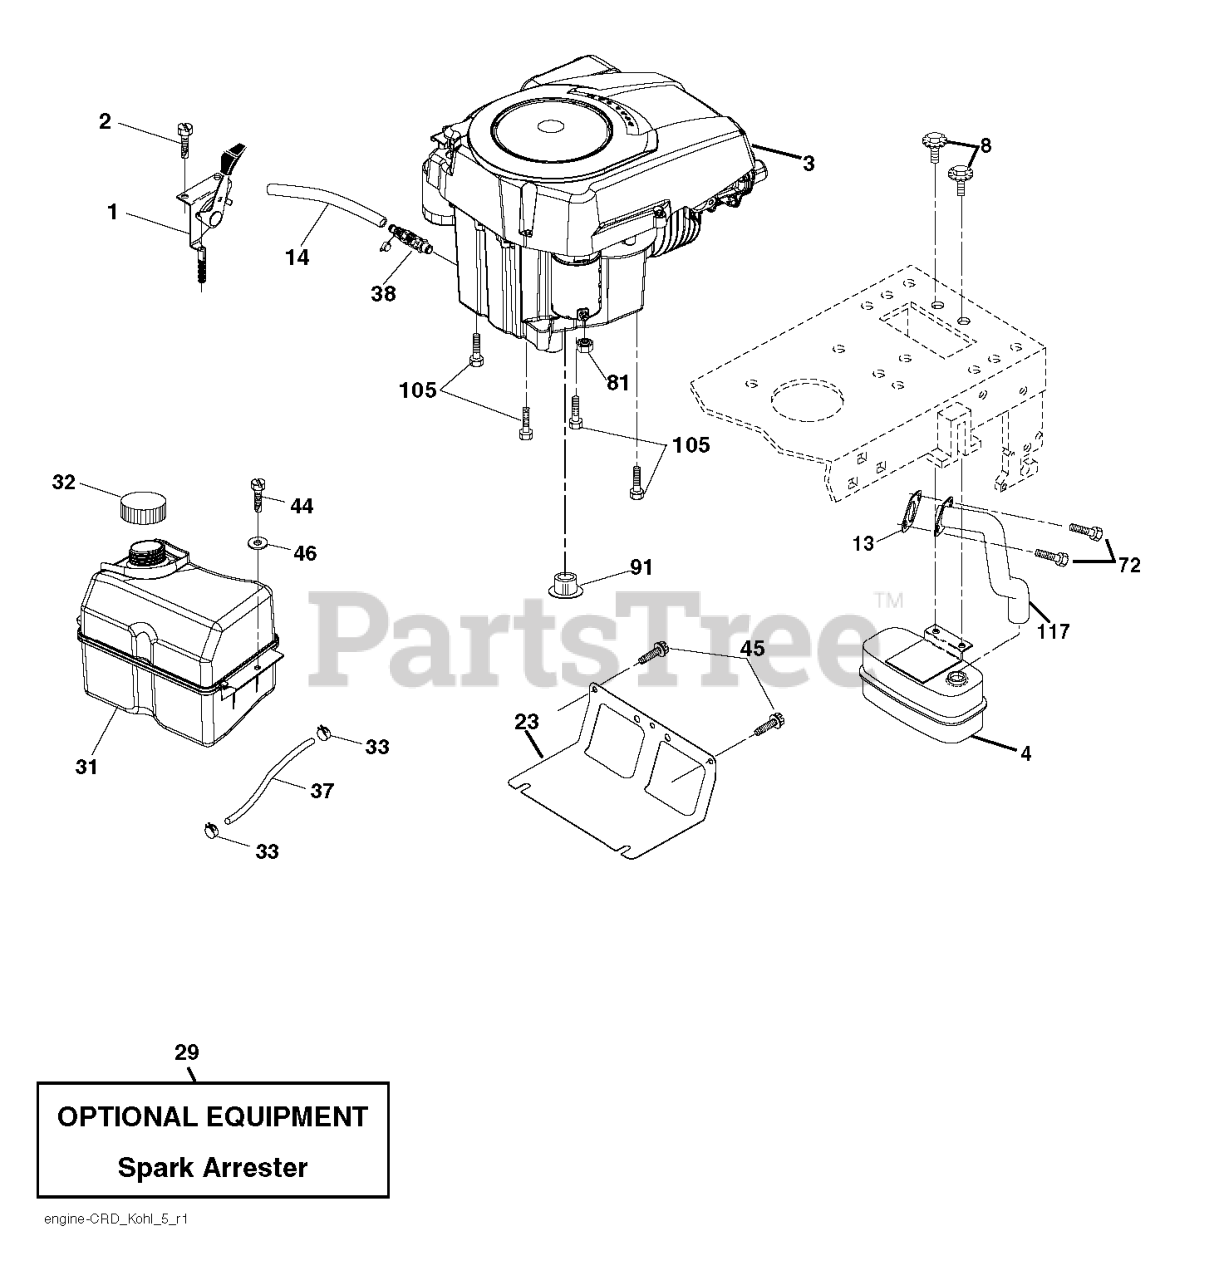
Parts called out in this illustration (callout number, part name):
1	CONTROL.TH/CK.C.
2	SCREW.#10 X 0.750.BOS
4	MUFFLER.SINGLE.CYL.KOHL/B&S
8	BOLT.5/16-18UNCX3/4 W/SEMS.BLK
13	GASKET.EXHAUST.KOHLER
14	TUBE, DRAIN OIL ASM.
23	SHIELD.BROWNING.DBR.GUARD
29	KIT.SPARK ARRESTOR 794945 B&S
31	RP TANK FUEL FRT 1.5 GAL
32	CAP.FUEL.2.25"VENTED"
33	HOSE CLAMP
37	LINE.FUEL.20
38	VALUE.OIL.DRAIN
44	SCREW HEXWSHR 1/4-20X3/4
45	SCREW, 3/8-16X3/4
72	SCREW.SOCKET HD.5/16-1
81	NUT
91	BUSHING.1.375OD
105	SCREW 3/8-16X1
117	RP.TUBE.EXHAUST.KOHL.COURAGE
